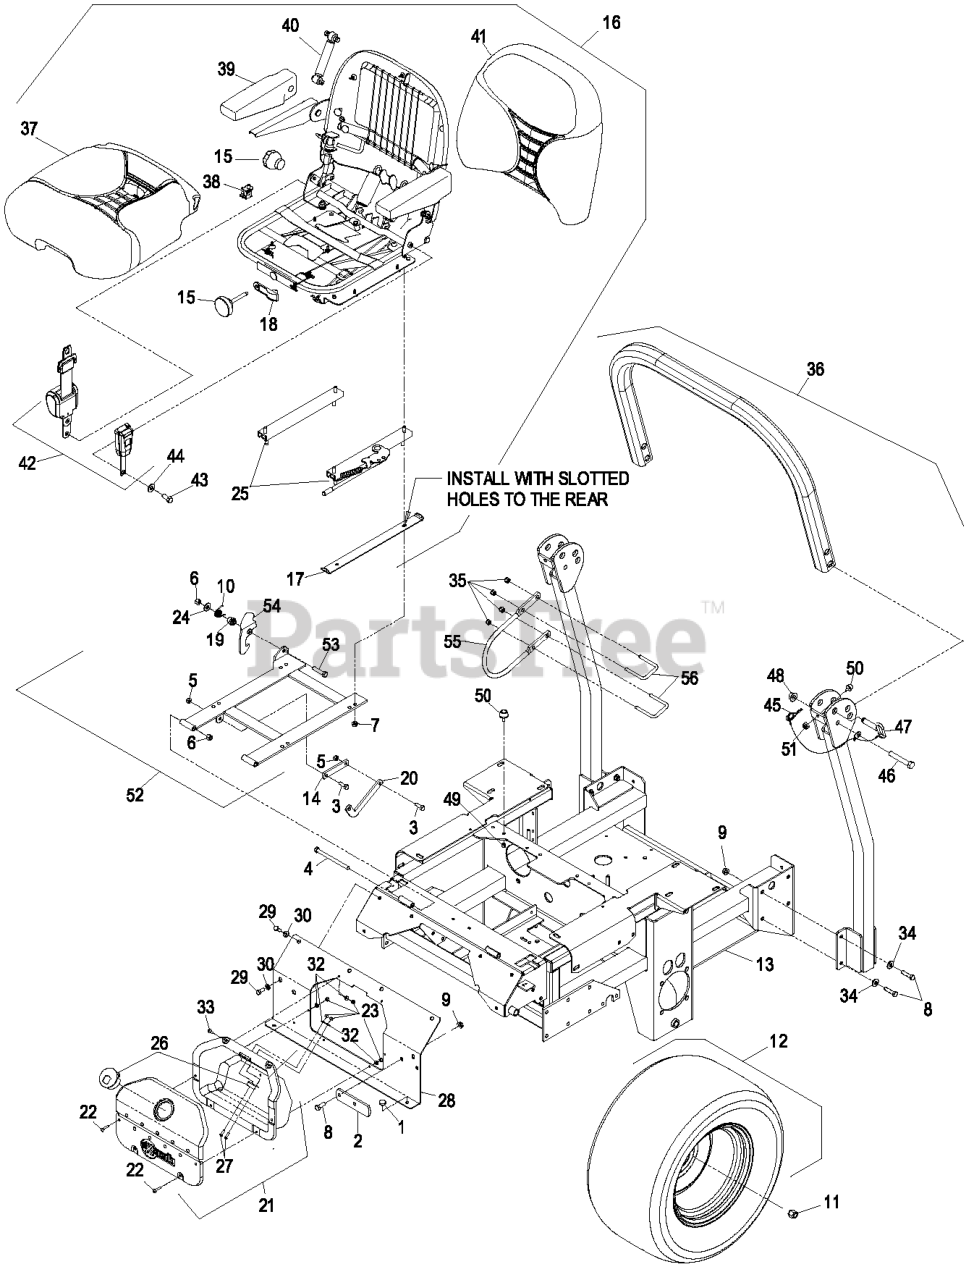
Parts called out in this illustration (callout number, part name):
2	STOP-BRAKE, PARK
3	SCREW-HH
4	SCREW-HH
5	NUT-LOCK, NI
6	NUT-LOCK, NI
8	SCREW-HH
9	NUT-HHF, WHIZ
10	SPRING-TORSION, LATCH
11	NUT-LUG
12	WHEEL AND TIRE ASM
13	ASM,XS ENGINE DECK W/DECA
14	LINK-STOP, SEAT
15	KNOB KIT
16	Seat, Suspension
17	STOP/SPACER-SEAT
18	WEIGHT INDICATOR KIT
19	BUSHING-LATCH, SEAT
20	LINK-STOP, SEAT
21	ASM,CUBBY
23	NUT-LOCK, NI
24	WASHER-FLAT
25	SEAT TRACK KIT
26	LATCH,CUBBY
27	SCREW-PPH
28	ASM, CONSOLE W/DECALS
29	SCREW-HH
30	WASHER-PLAIN
32	WASHER-FLAT
33	SCREW-HEAD, TRUSS
34	WASHER-BELLEVILLE
35	NUT-LOCK, NI
36	KIT, 06 XS ROPS
37	BOTTOM CUSHION KIT
38	SWITCH-BAIL
39	PAD-ARMREST
40	SHOCK ABSORBER KIT
41	BACK CUSHION KIT
42	RETRACTABLE SEATBELT KIT
43	SCREW-HH
44	WASHER-SPRING
45	HAIRPIN
46	SCREW-HH
47	PIN-FOLD, ROPS
49	NUT-LOCK, NI
50	BUMPER-RUBBER
51	NUT-LOCK, NI
52	KIT,SEAT FRAME SERVICE
53	SCREW-HH
54	CATCH-LATCH, SINGLE
